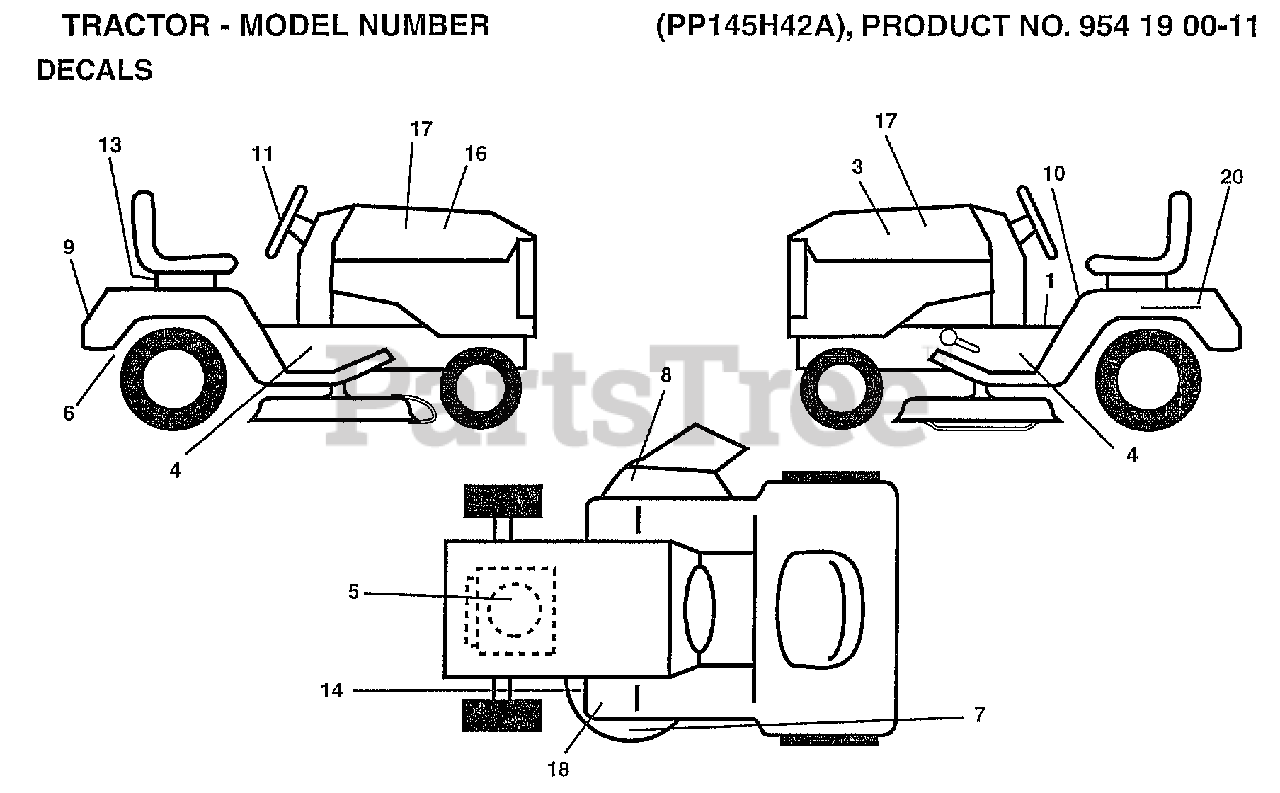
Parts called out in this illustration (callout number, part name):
1	DECAL SADDLE OPER
3	DECAL HOOD LH
4	"DECAL CHASSIS 42"""
5	DECAL HP ENGINE
6	DECAL DRAWBAR LH
7	"DECAL,ENVIRO DECK"
8	"DECAL, WARNING"
9	DECAL, FENDER
10	DECAL.CAUT.ENG/FR
11	DECAL, SCL COLD START HYD
13	RETAINER-SPRING
14	DECAL
16	DECAL HOOD RH
17	DECAL DOMED
18	DECAL T
20	DECAL.BATRY.3-3908
